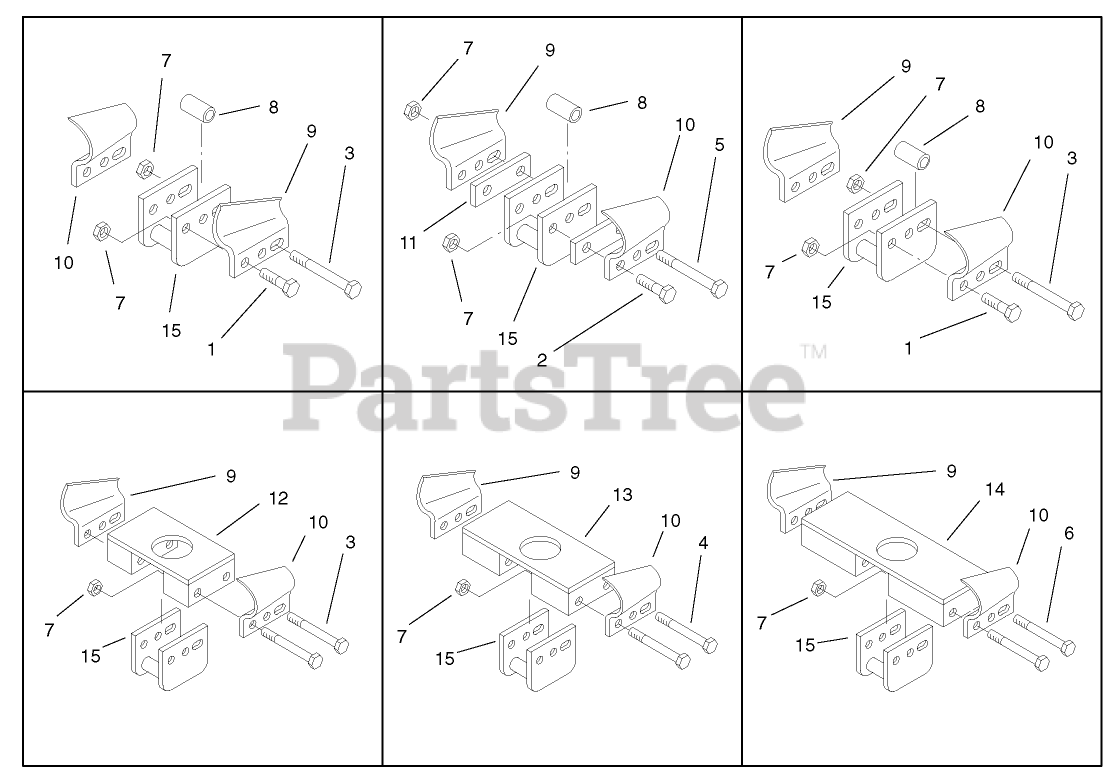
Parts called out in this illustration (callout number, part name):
1	SCREW-HH
2	SCREW-HH
3	SCREW-HH
4	SCREW-HH
5	SCREW-HH
6	SCREW-HH
7	Nut
8	SPACER-TUBE
9	TOOTH-RH,SOIL
10	TOOTH-LH,SOIL
11	SPACER - 6"
12	ADAPTER - 8"
13	ADAPTER - 10"
14	ADAPTER - 12"
15	CHAIN - 64 PITCHES
